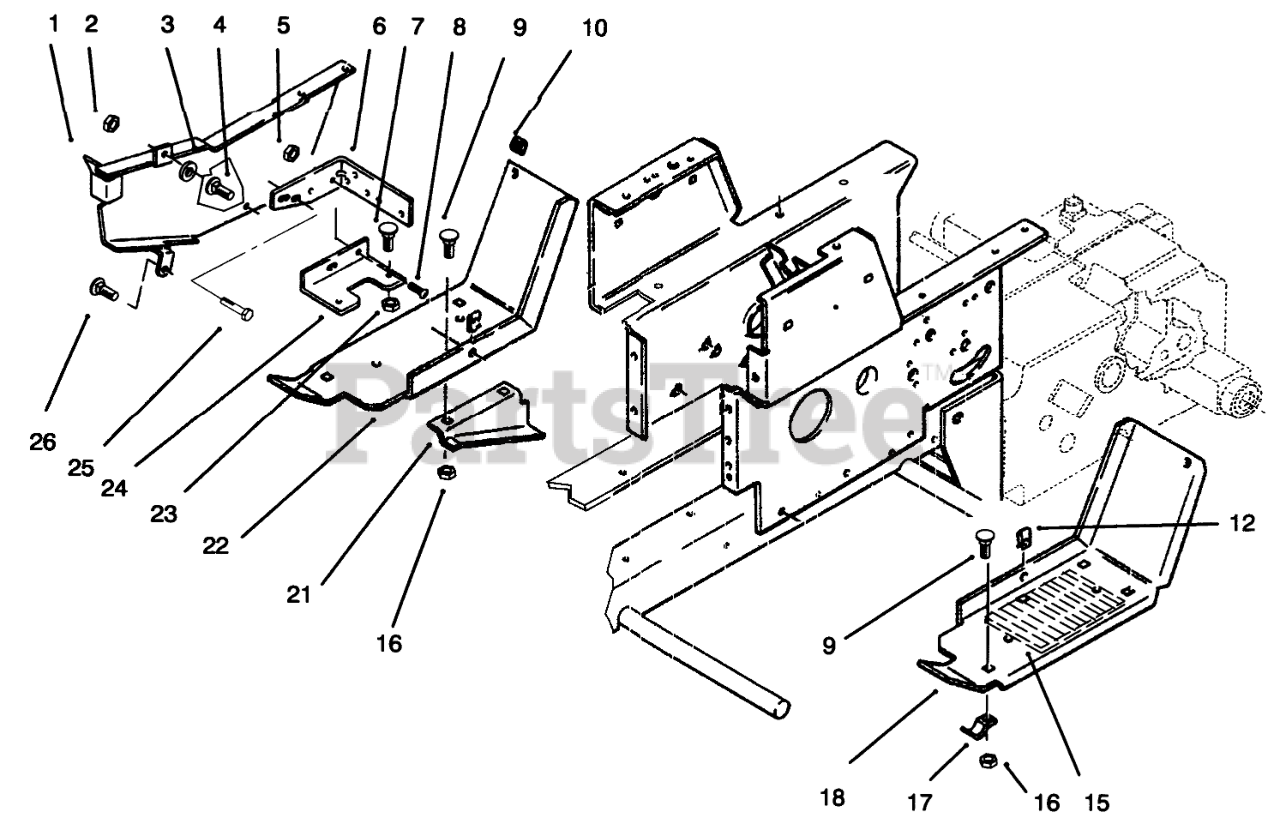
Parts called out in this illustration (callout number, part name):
1	Belt Guard
2	NUT-LOCK, NI
3	NUT-PUSH
4	SCREW-PPH
5	NUT-LOCK, NI
6	BRACKET-BELTB
7	SCREW-PAN
8	SCREW-HH
9	BOLT-CARR
10	BUMPER
15	PAD FOOTREST
16	NUT-LOCK, NI
17	BRACKET
18	FOOTREST LH R
21	GUID-LOWER BLTR
22	Footrest-RH
23	Nut
24	BRKT-FUS HLDERB
25	BOLT-CARR
26	Bolt
